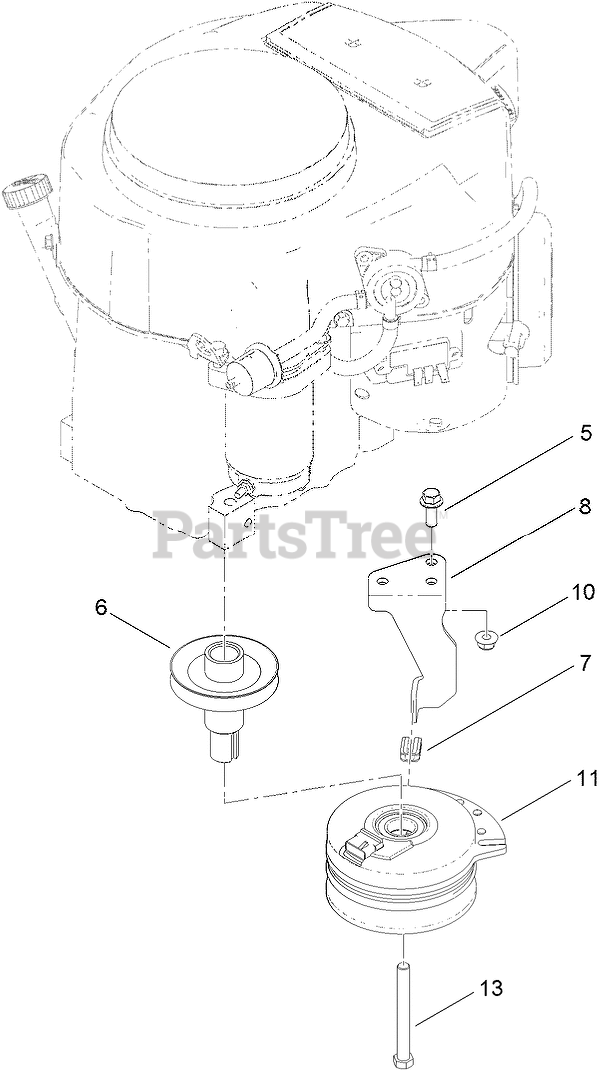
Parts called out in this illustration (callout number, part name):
5	SCREW-HHF
6	PULLEY-ENGINE
7	ISOLATOR-CLUTCH
8	STOP-CLUTCH
10	NUT-HF, NI
11	CLUTCH-ELECTRIC
13	SCREW-HH
